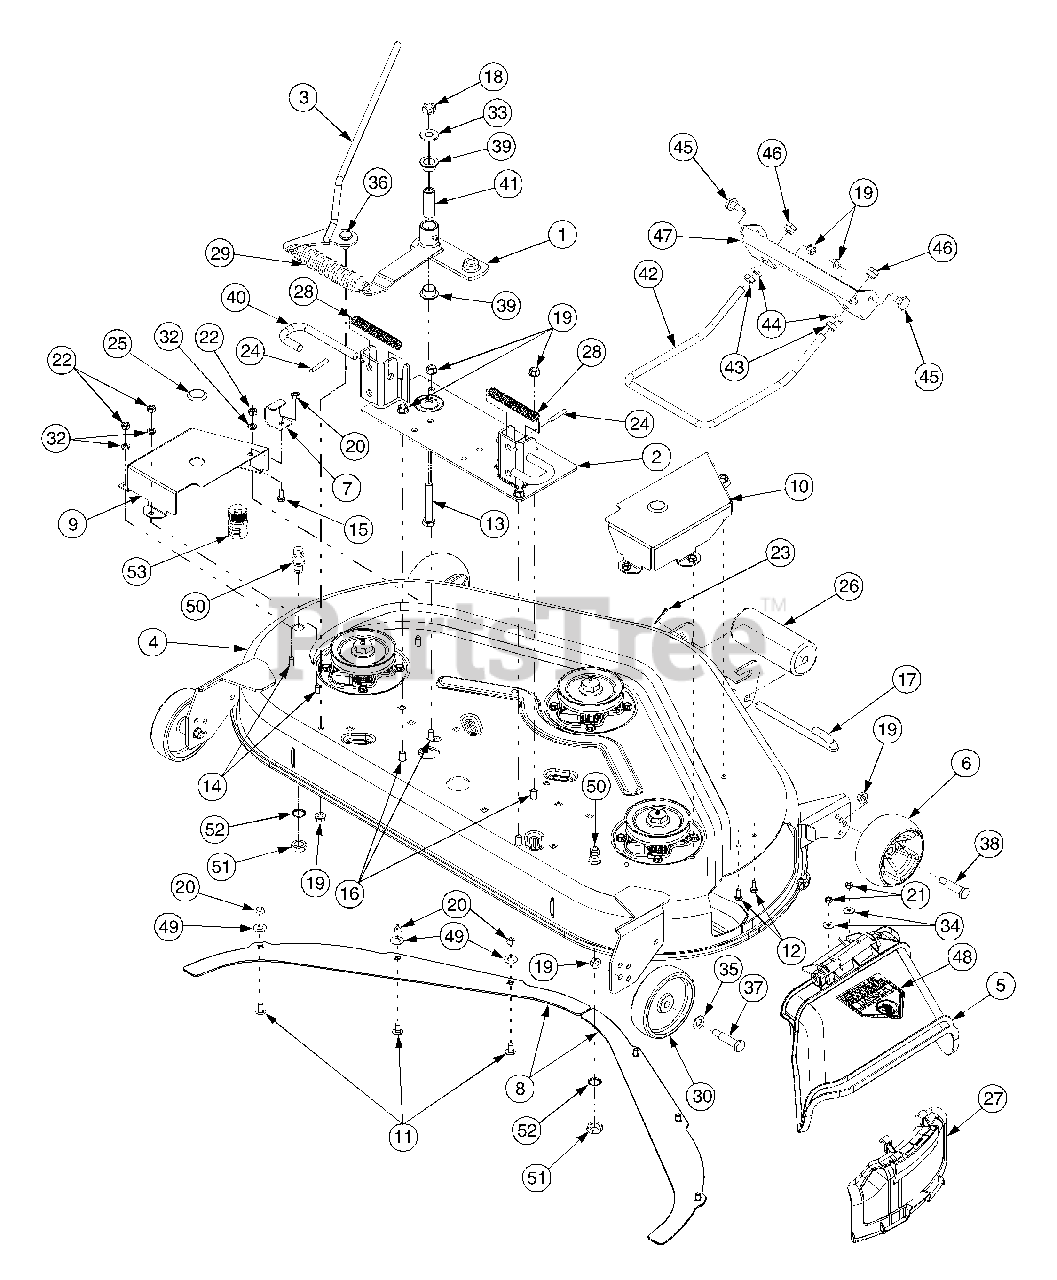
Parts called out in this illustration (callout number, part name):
1	Idler Assembly
5	Chute Assembly, Discharge
6	Wheel, Deck w/Fitting
11	Bolt, Carriage, 5/16-18 x .62
12	Screw, Hex Cap, 1/4-20 x .62
13	Screw, Hex Cap, 1/2-20 x 3.0
14	Screw, Self Tap, 5/16-18 x .75
15	Screw, Hex Cap, 5/16-18 x .75
16	Bolt, Carriage, 3/8-16 x .75 GR5
17	Pin, Roller, 1/2 Dia x 7.31
18	Nut, Hex Lock, 1/2-20
19	Nut, Flange Lock, 3/8-16
20	Nut, Flange Lock, 5/16-18
21	Nut, Hex, 1/4-20 GR5
22	Nut, Hex, 5/16-18, GR5
23	Pin, Cotter, 1/8 Dia x 1
24	Pin, Spiral Spring, 3/16 Dia x .75
25	Button Plug
26	Front Roller
27	Plug, Mulch
28	Spring, Comp, .66 OD x 1.8
29	Spring, Ext, .162 Dia x 1.25 OD
30	Wheel, Deck, 5.0 x 1.38
32	Washer, Lock, 5/16
33	Washer, Flat, 1/2 x 1.25 x .10
34	Washer, Bell, .265 x .75 x .062
35	Washer, Flat, .510 x 1 x .060
36	Bolt, Shoulder, .498 Dia x .340
37	Screw, Shoulder, .498 x 1.635
38	Bolt, Shoulder
39	Bearing, Flange, 3/4 ID x .52 LG
40	Pin, Mower Support
41	Spacer, .5 OD x .75 x 2.07 Lg
42	Rod, Front Lift
43	Nut, Hex Jam, 1/2-13 GR5
44	Washer, Lock, 1/2
45	Bolt, Shoulder, .50 Dia. x .494 Lg
46	Nut, Hex Insert Lock, 1/2-13
48	Graphic, Danger
49	Washer, Flat, .474 x .88 x .064
50	Nozzle, Deck Wash
51	Nut, Hex M16-1.5
52	Washer, Lock
53	Adapter, Water Nozzle
